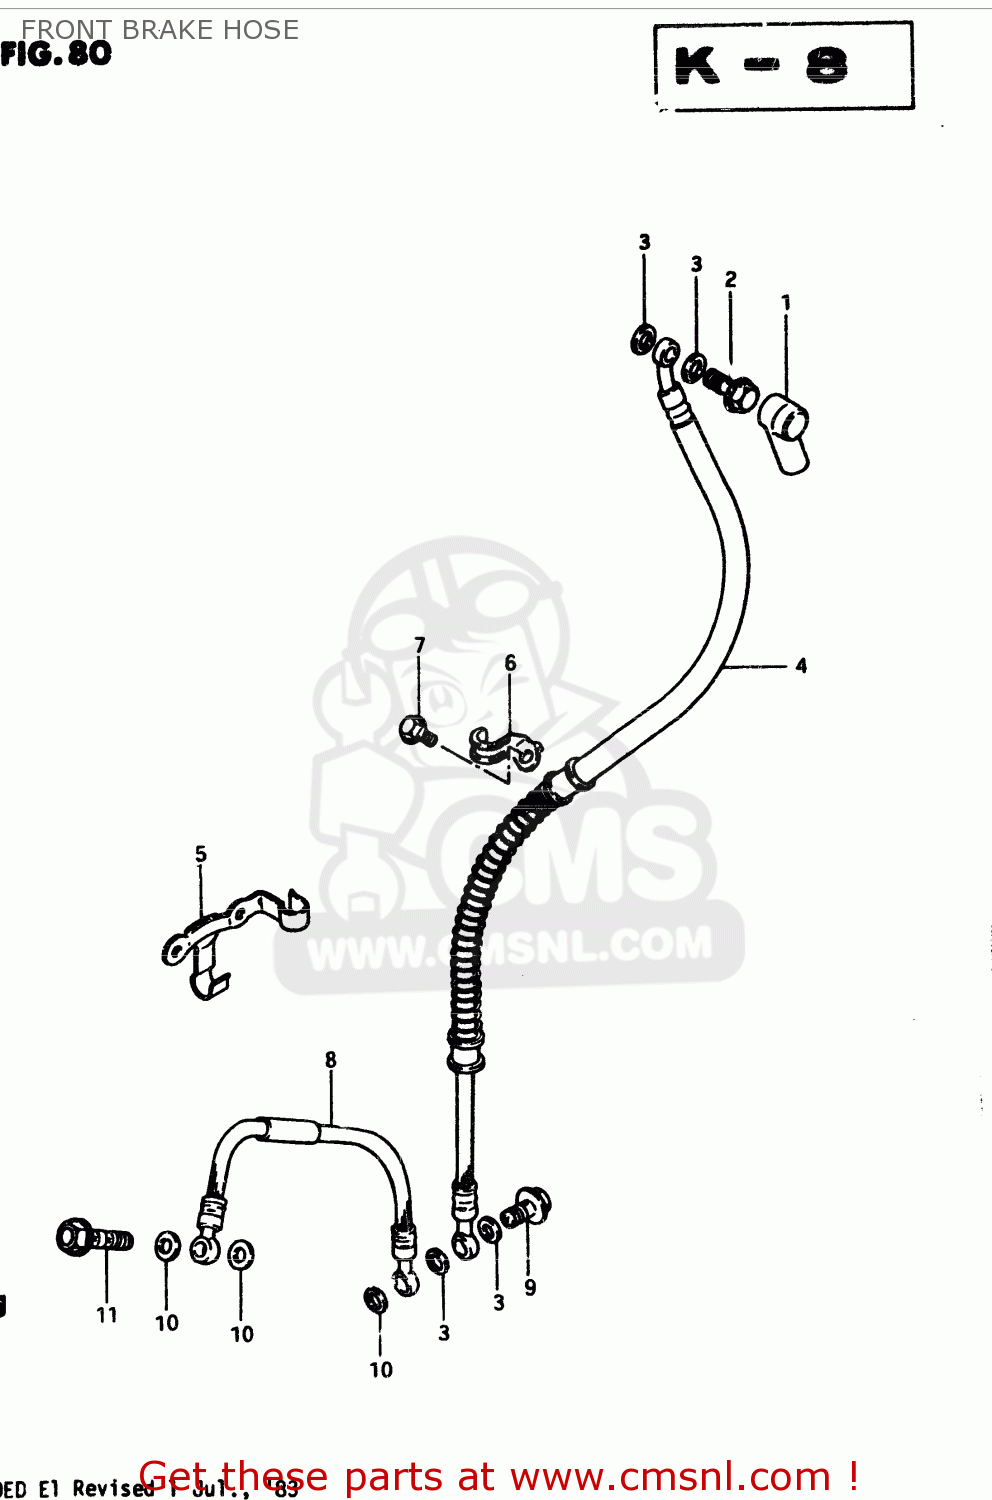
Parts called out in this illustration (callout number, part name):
1	BOOT,MASTER CYLINDER
2	BOLT,UNION
3	WASHER
4	HOSE,FR BRAKE
5	CLAMP,BRAKE HOSE,LEFT
6	GUIDE,BRAKE HOSE NO.3
7	BOLT
8	HOSE,ANTI NOSE
9	BOLT,UNION
10	WASHER
11	BOLT UNION
